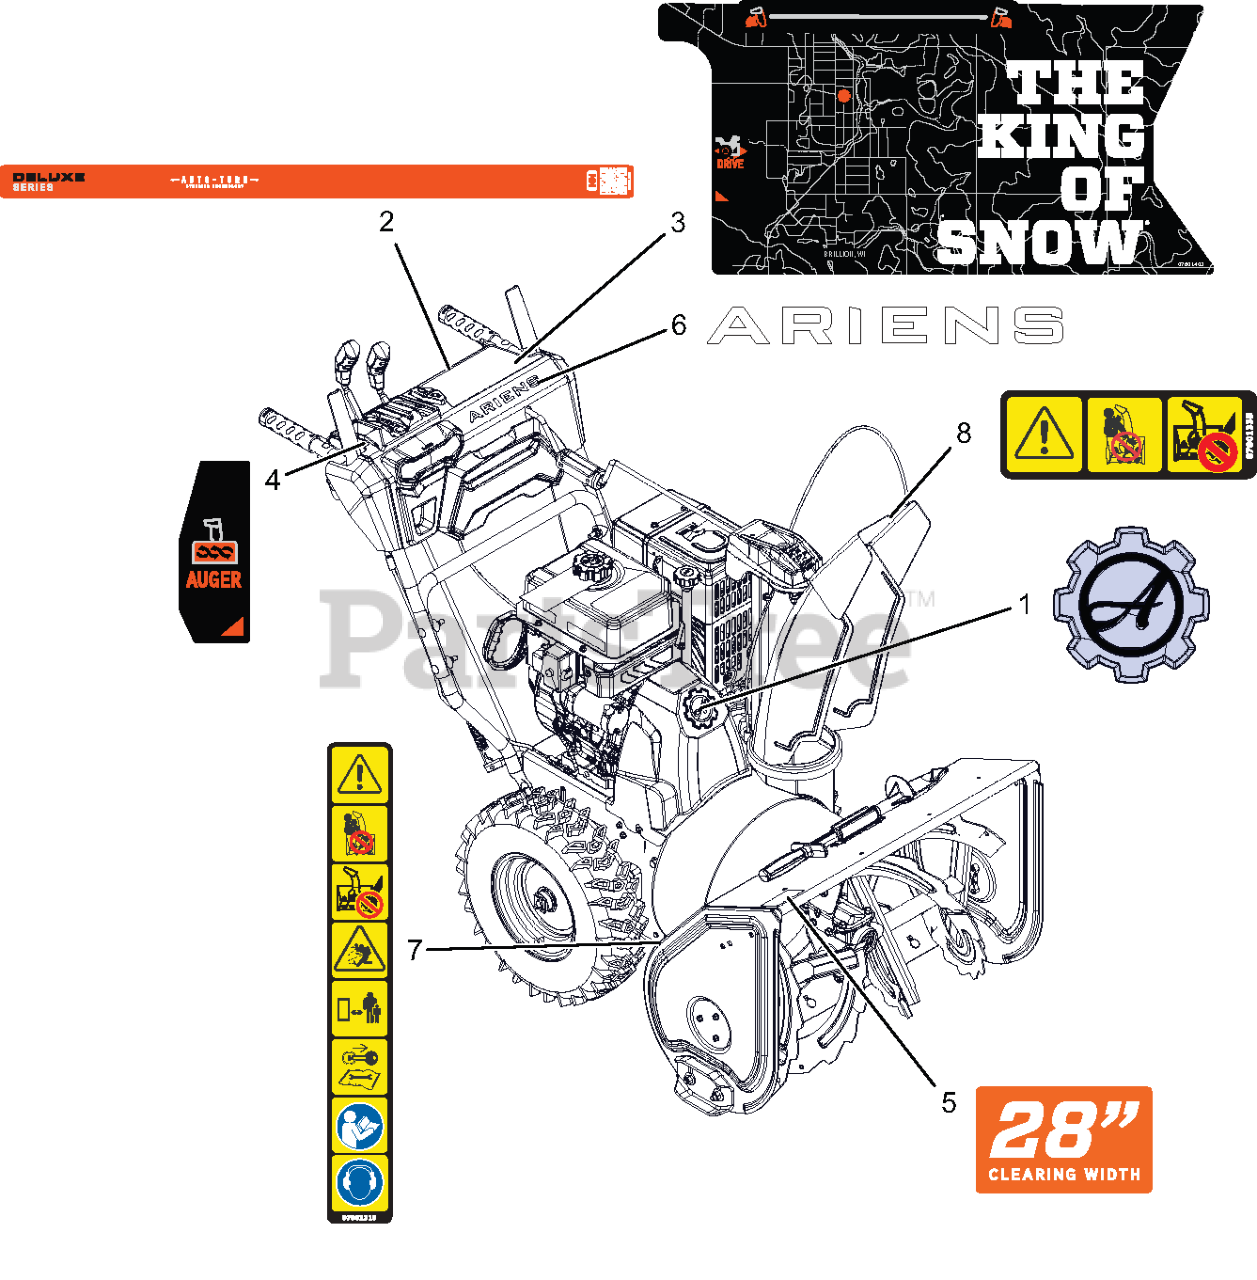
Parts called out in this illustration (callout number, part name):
1	DECAL- ARIENS GEAR BADGE
2	DECAL- DASH - DLX
3	DECAL-CONTROL-LG CHUTE ROTATE
4	DECAL- CONTROL - AUGER
5	DECAL- CLEARING - 28
6	DECAL- ARIENS - 7.46"
7	DECAL- SAFETY - DANGER
8	DECAL- DANGER
